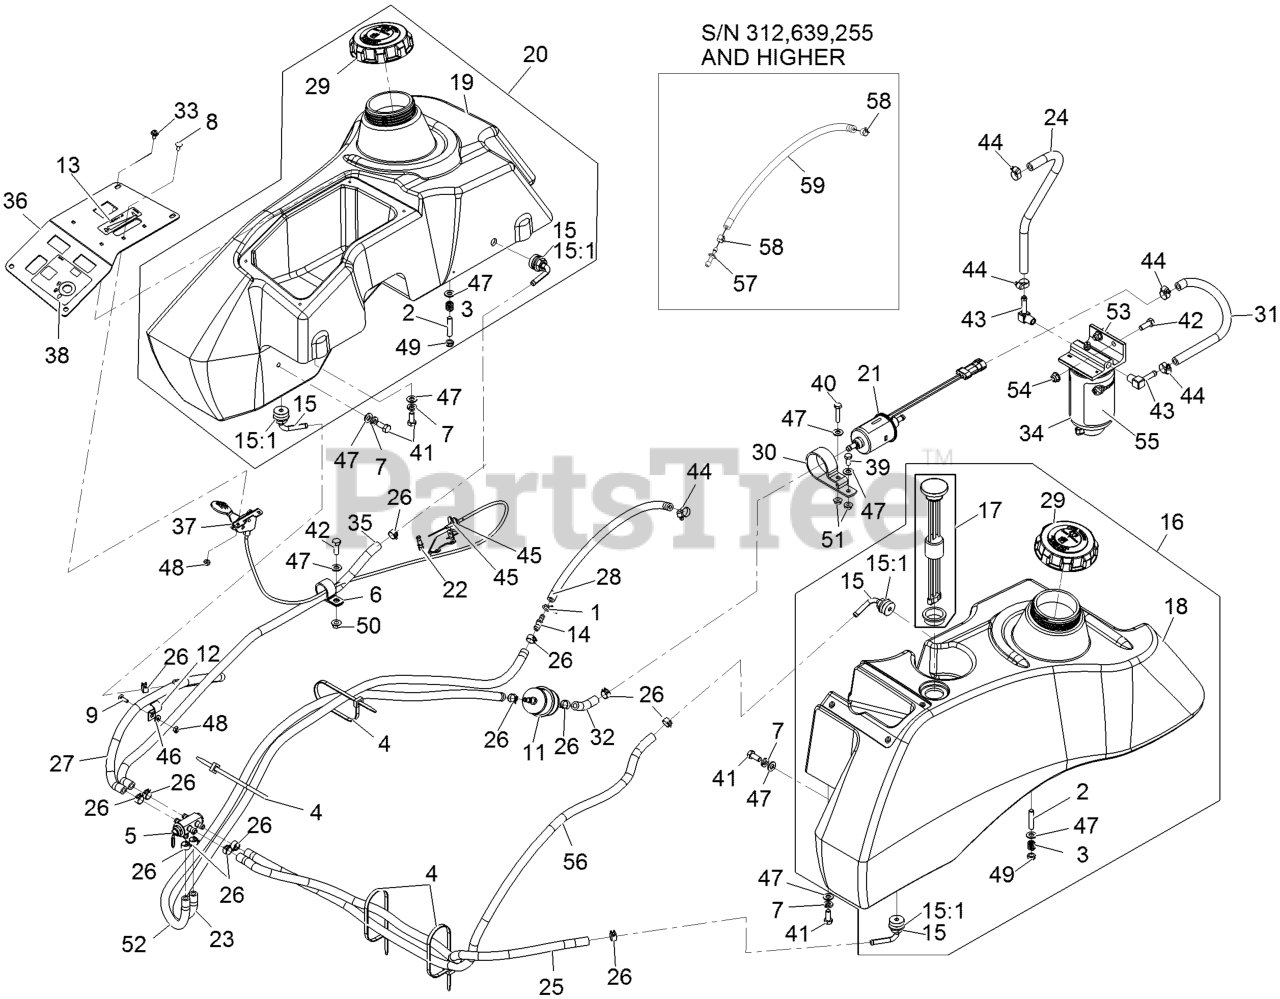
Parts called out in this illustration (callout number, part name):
2	STUD
3	SPRING-TANK, FUEL
4	TIE-PLASTIC
5	VALVE,FUEL SELECTOR 5/16
6	CLIP-LOOM
7	WASHER-LOCK
8	BOLT-CARR
9	BOLT-CARR
11	FILTER-INLINE
12	CLIP-HALF, LOOM
13	DECAL,THROTTLE ONLY
14	CONNECTOR
15	FITTING,FUEL BULKHEAD W/O
15:1	O-RING,BULKHEAD FITTING
16	ASM,FUEL TANK LXS LH
17	KIT, CT FUEL GAGE REPL.
18	ASM, Fuel Tank Lxs LH
19	Asm, Fuel Tank Lxs Rh
20	ASM, FUEL TANK LXS RH
21	PUMP-FUEL
22	SWIVEL-STOP, CABLE
23	HOSE-FUEL
24	HOSE-FUEL
25	HOSE-FUEL
26	CLAMP-HOSE
27	HOSE-FUEL
28	HOSE-FUEL
29	CAP-BIODIESEL
30	BRACKET-PUMP, FUEL
31	HOSE-FUEL
32	HOSE-FUEL
33	SCREW-PPH
34	FILTER-FUEL
35	HOSE-FUEL
36	CONTROL PANEL W/DECALS
37	CABLE,THROTTLE
38	DECAL-CONTROL PANEL
39	SCREW-HH
40	SCREW-HH
41	SCREW-HH
42	SCREW-HH
43	FITTING-HYD, 90 DEG
44	CLAMP-WORM
45	NUT-JAM
46	WASHER-FLAT
47	WASHER-PLAIN
48	NUT-LOCK, NI
49	NUT-LOCK, NI
52	HOSE-FUEL
53	FUEL FILTER ASM
54	NUT-HF, NI
55	Decal,Exmark Filter
56	HOSE-FUEL
57	FITTING-STRAIGHT
58	CLAMP-HOSE
59	HOSE-FUEL
